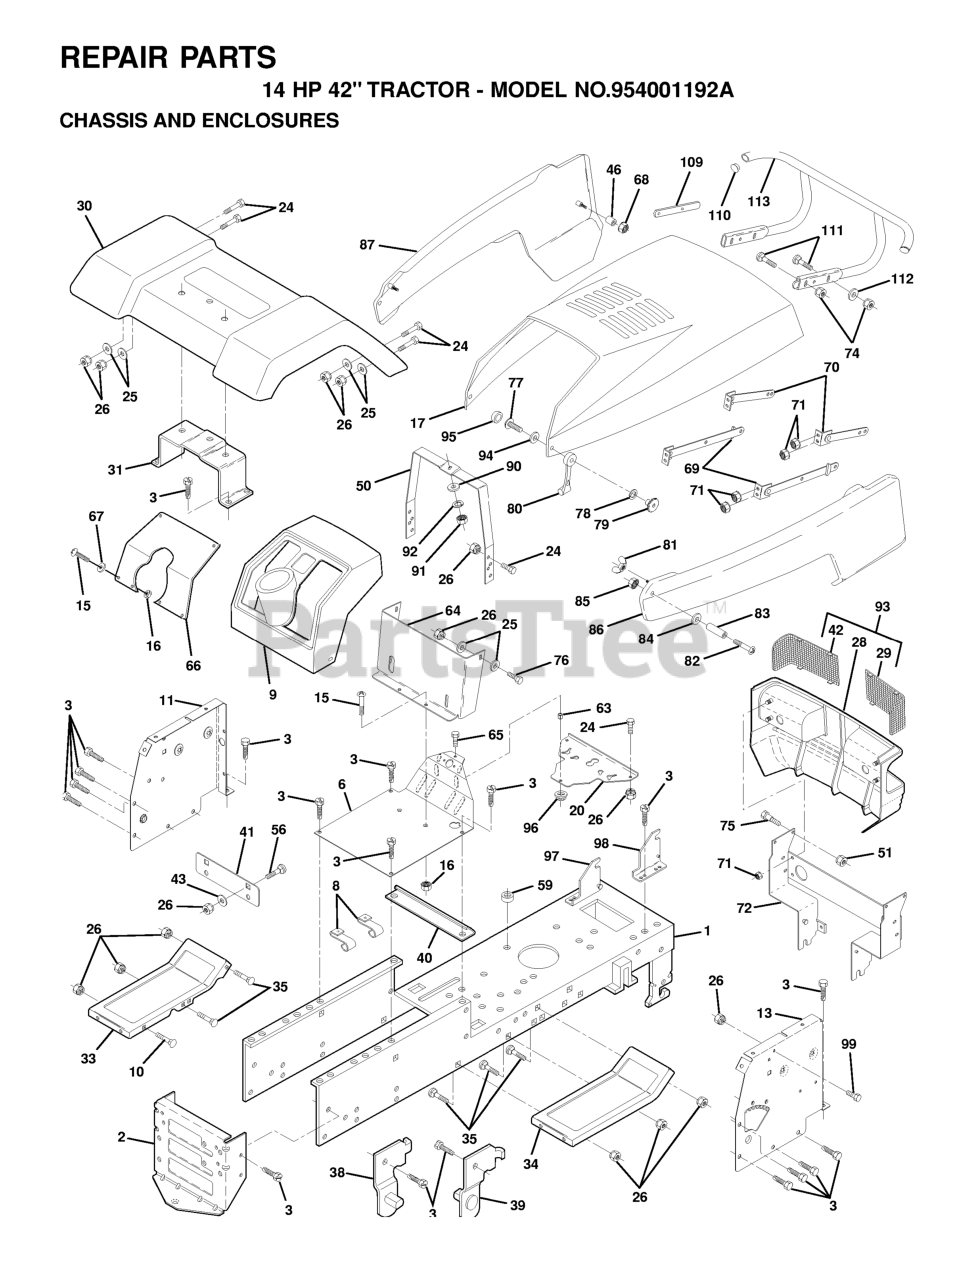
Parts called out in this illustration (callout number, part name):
1	CHASSIS
2	STRETCH DRAWBAR
3	SCREW
8	CLIP,INSULATOR
10	BOLT D
11	PANEL DASH LH
13	PANEL DASH RH
15	Screw, Machine, Truss Head 5/16-18 UNC x 3/4
16	NUT
17	HOOD.HUSQVARNA.ORANGE
20	PLATE, BATTERY
25	WASHER
26	NUT
28	GRILL
29	LENS RH
30	FENDER
31	BRACKET.SUPPORT.FENDER
33	ROLL PIN NLA
34	PAD,SPACER
38	BRACKET LH PIVOT
39	BRACKET RH PIVOT
41	PLATE
42	LENS LH
43	Washer 1 17/32 X 7/8 X 16 Ga
50	SUPPORT ASS'Y
51	LOCKNUT.NYLOC.1/4-20
56	Bolt - Rd. Hd. Sq. Neckiage 3/8 16 x 3/4
59	SNAP BUSHING T
64	DASH ASSY LT NLA
65	Bolt Fin Hex 5/16 - 18 Unc x 2 Gr. 2
66	DASH PLATE
67	WASHER
68	NUT
69	STRAP ASSY LT
70	STRAP ASSY LT
71	Nut, Keps Blk Hex 1/4-20 UNC
72	SUPT, ASS'Y GRILL
75	BOLT T
76	BOLT
77	SCREW
78	LOCKWASHER #10
79	WELDNUT
80	LATCH.HOOD.
81	WING NUT
82	RP SCREW
85	NUT **
86	PANEL SIDE RH
87	PANEL SIDE LH
91	NUT
92	LOCKWASHER
93	GRILL
95	SNAP CAP LT
96	NUT.71038.31-18.HEX.NYLOCK
97	SUPPORT RH YTH
98	SUPPORT LH YTH
99	BOLT
109	BRACKET BUMPER
110	PLUG PLASTIC
111	BOLT.3/8-14X1.25
112	WASHER
113	BUMPER ASSY
